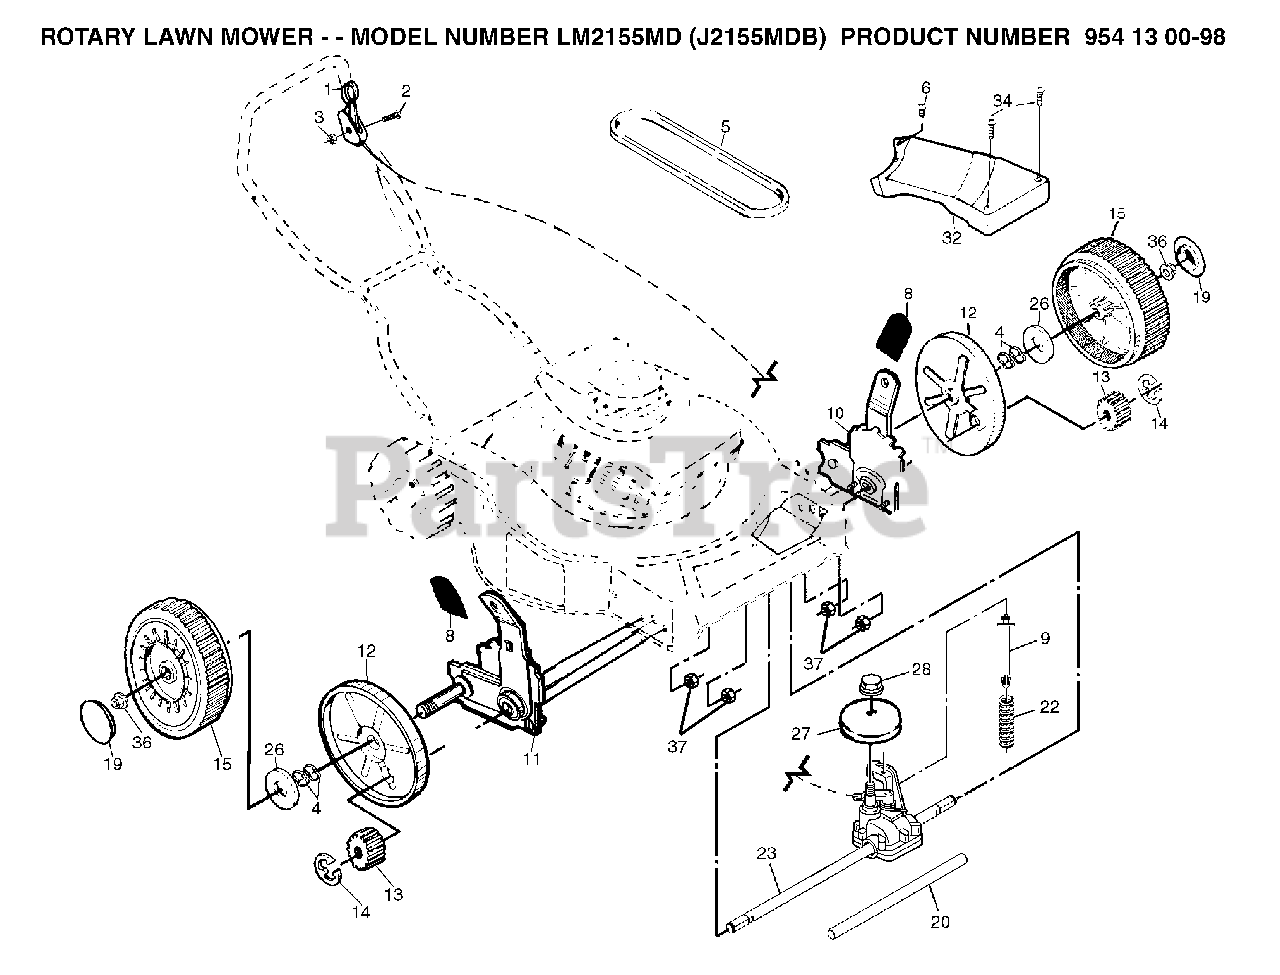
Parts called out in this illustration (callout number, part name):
1	DRIVE CONTROL 59.8 FWGD
4	WAVE WASHER
5	BELT THERM .32
6	TAPPING SCREW
8	SELECTOR KNOB
9	SPRING RETAINER
12	DUST COVER, WHEEL
13	PINION GEAR
14	E-RING 7/16 RE
15	WHEEL.8X2.RADIAL.GRAY
20	DRV SHAFT TUBE PM
22	SPRING.EXTENSION
23	TRANSMISSION 22RD
26	WASHER FLUT
27	PULLEY
28	FLANGED LOCKNUT 3/8-16 ZINC
36	HEX FLANGE LOCKNT
37	LOCKNUT
